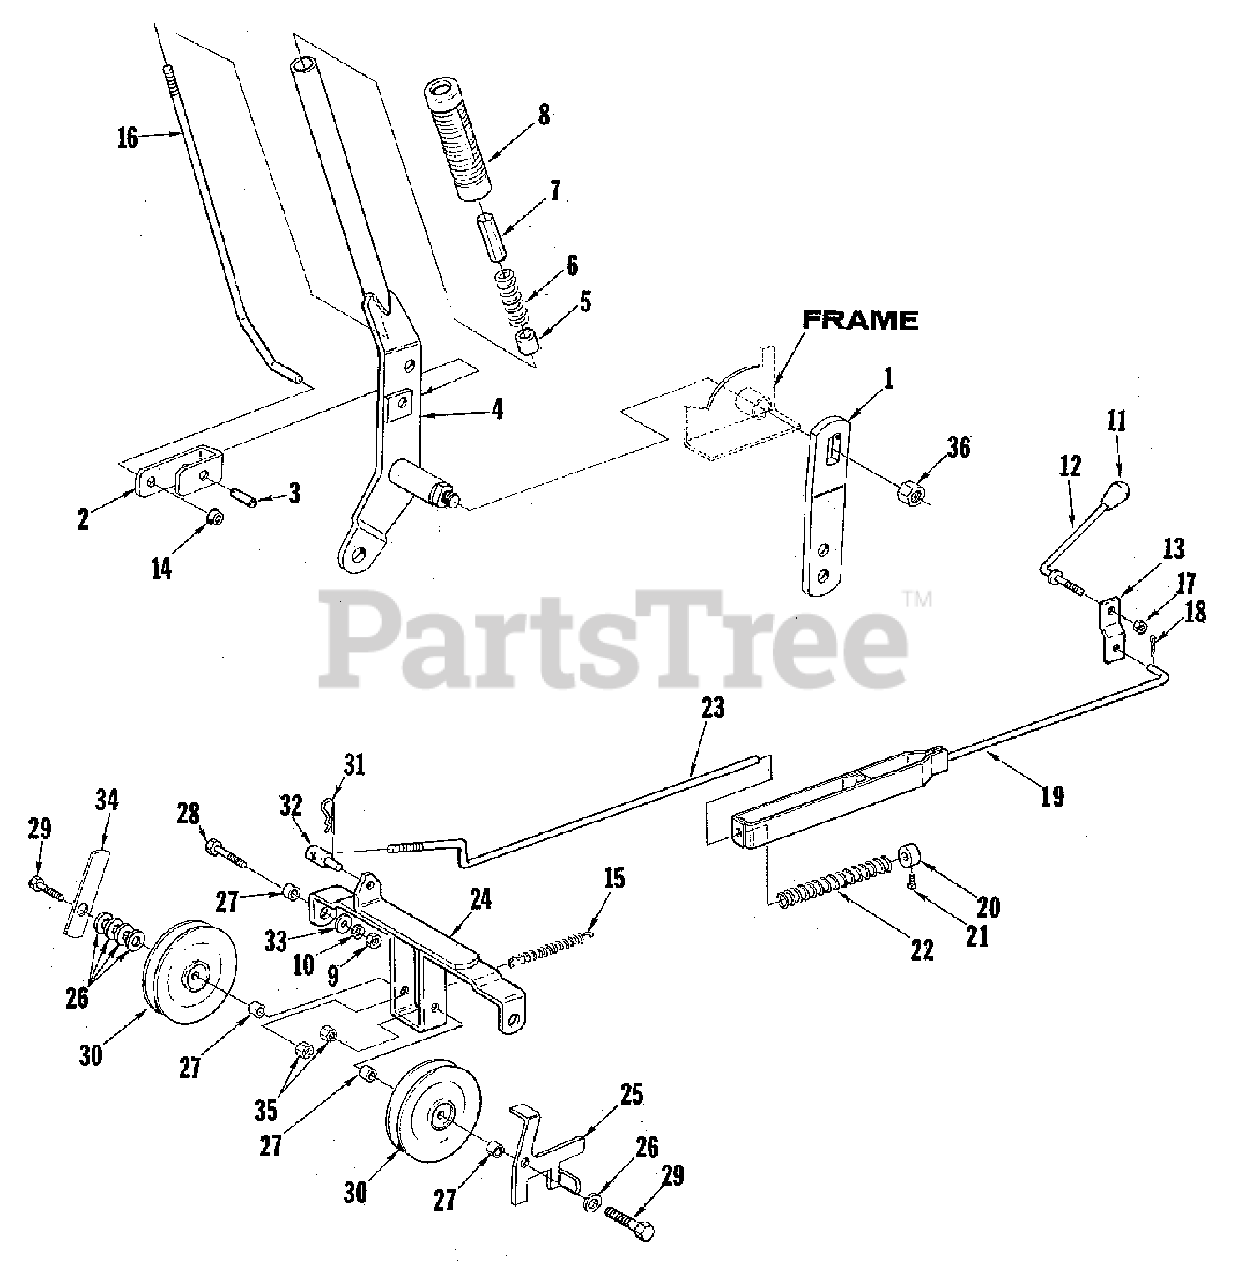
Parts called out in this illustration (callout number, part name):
1	LINK, Lift Lever
2	LATCH, Lift Lever
3	PIN, Spring, 3/8 x 1
7	BUTTON, Thumb
8	GRIP, Handle
9	NUT, Hex Fin, 3/8-16
10	LOCKWASHER, 3/8
12	HANDLE, Clutch Control
14	FASTENER, Nut
15	SPRING, Tension
17	NUT, Lock, Hex, 3/8-16
19	GUIDE ASSEMBLY, PTO
21	SETSCREW, Square Head, 1/4-20 x 3/8
22	SPRING, Compression
24	CLEVIS ASSEMBLY, Pulley
26	WASHER, Flat, 5/16
28	CAPSCREW, Hex Head, 3/8-16 x 1
29	CAPSCREW, Hex Head, 3/8-16 x 2
31	CLIP, Spring
32	PIVOT, Rod End
33	WASHER, Flat, 3/8
35	NUT, Flange Wizlock, 3/8-16
36	NUT, Hex Jam, 1/2-13
